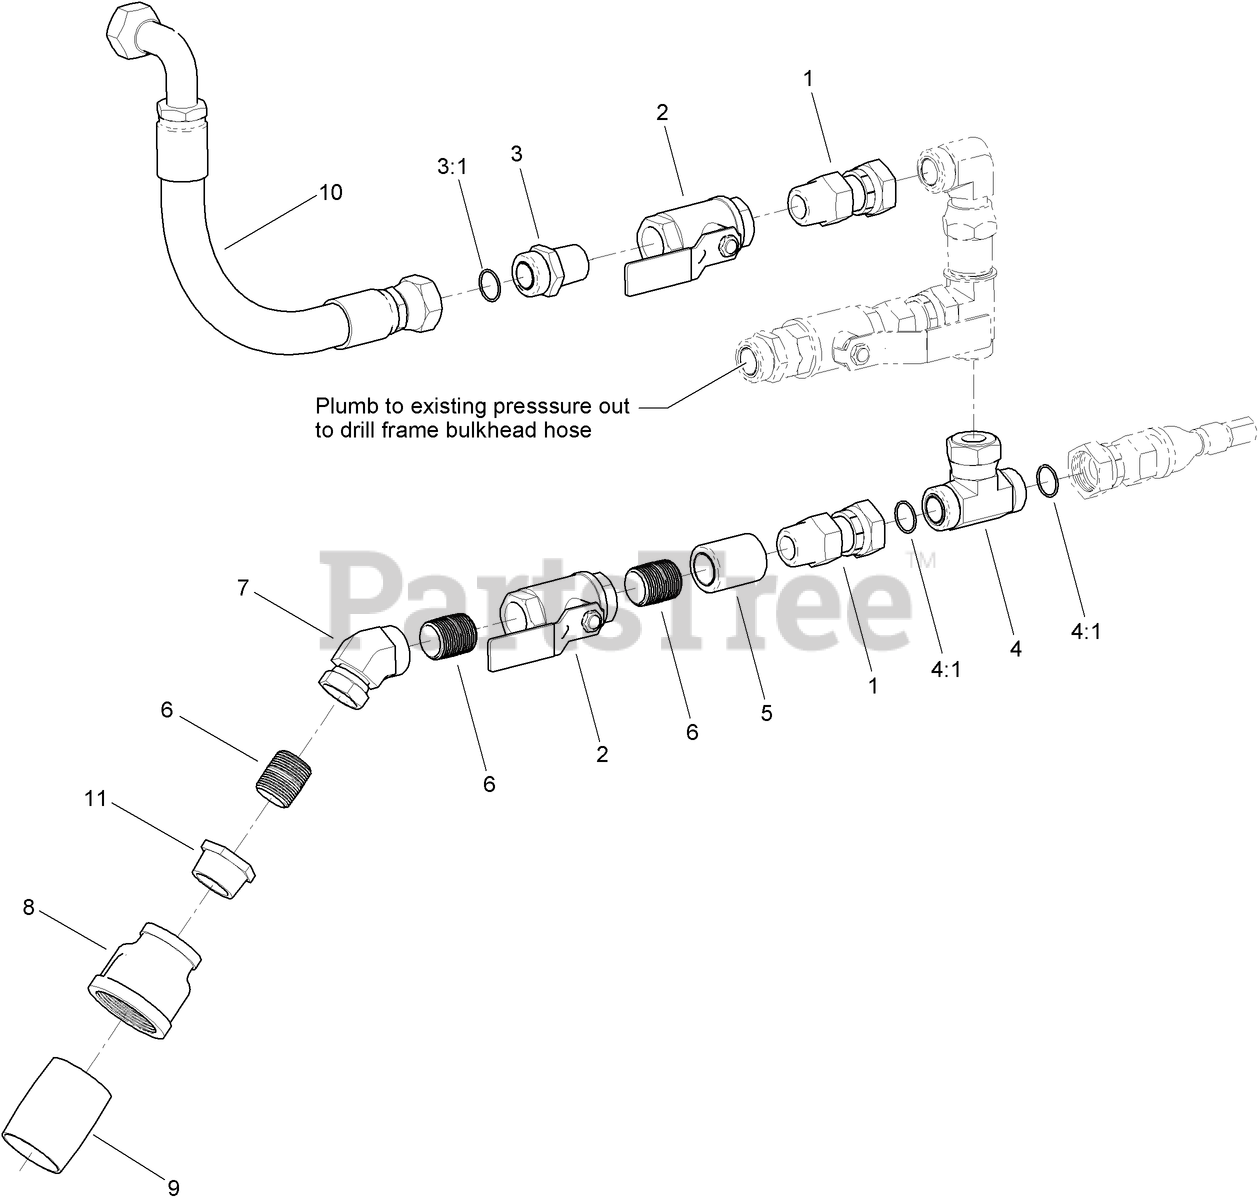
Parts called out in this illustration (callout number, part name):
1	FITTING-STRAIGHT
2	VALVE-BALL
3	FITTING-STRAIGHT
3:1	O-RING
4	FITTING-TEE
4:1	O-RING
5	COUPLING-PIPE
6	NIPPLE-PIPE
7	FITTING-ELBOW, 45 DEG
8	FITTING-REDUCER, BELL
9	NIPPLE-PIPE
10	HYD HOSE ASM
11	FITTING-REDUCER
